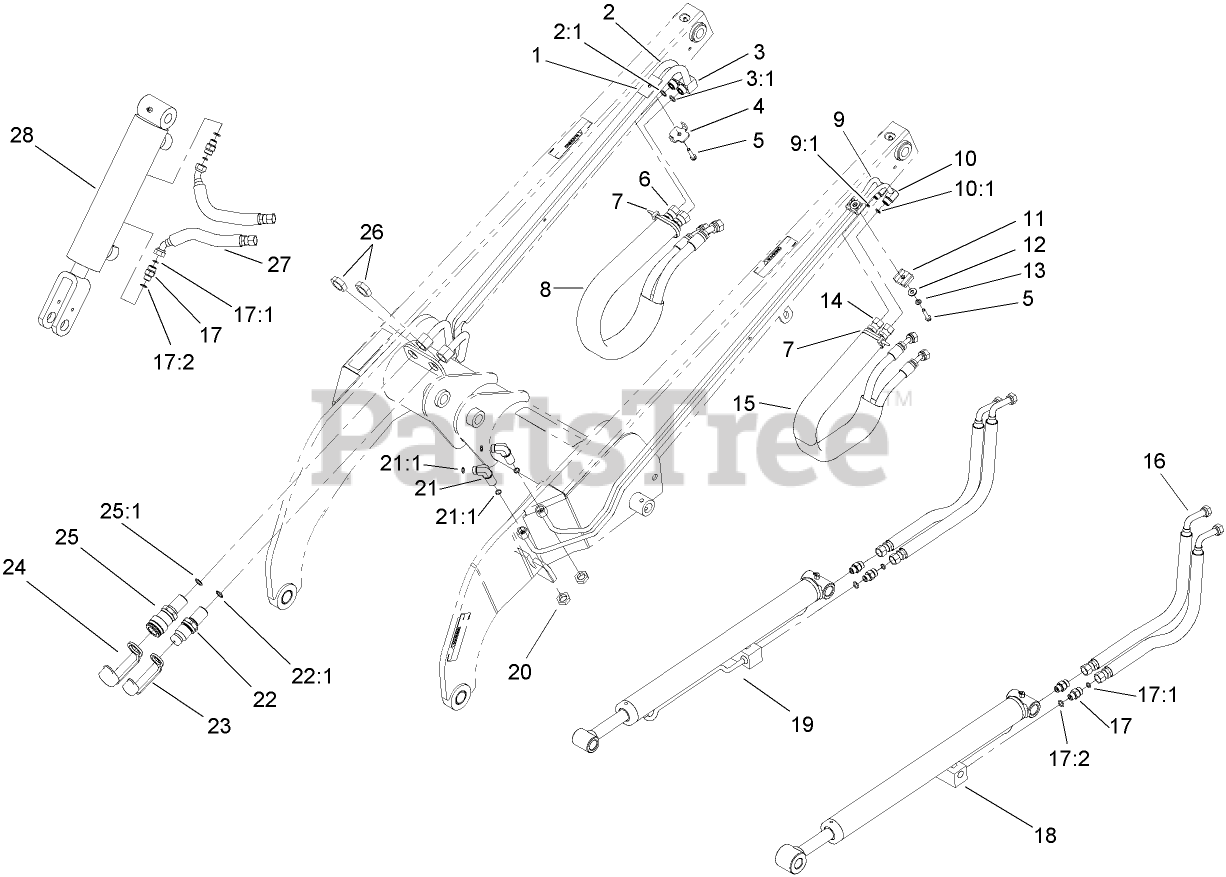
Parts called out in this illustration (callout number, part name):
1	SPACER-HARDLINE
2	HYD TUBE ASM
2:1	O-RING
3	HYD TUBE ASM
3:1	O-RING
4	PLATE-CLAMP, TUBE
5	SCREW-HWH
6	HOSE-HYD
7	TIE-CABLE
8	SLEEVE-PROTECTIVE
9	HYD TUBE ASM
9:1	O-RING
10	HYD TUBE ASM
10:1	O-RING
11	CLAMP-TUBE
12	WASHER-FLAT
13	WASHER-LOCK
14	HOSE-HYD
15	SLEEVE-PROTECTIVE
16	HOSE-HYD
17	FITTING-STRAIGHT
17:1	O-RING
17:2	O-RING
18	LH LIFT CYLINDER ASM
19	RH LIFT CYLINDER ASM
20	NUT-LOCK
21	UNION-BULKHEAD
21:1	O-RING
22	BULKHEAD NIPPLE ASM
22:1	O-RING
23	CAP-DUST, NIPPLE
24	CAP-DUST, COUPLER
25	BULKHEAD COUPLER ASM
25:1	O-RING
26	NUT-LOCK, BULKHEAD
27	HOSE-HYD
28	TILT CYLINDER ASM
